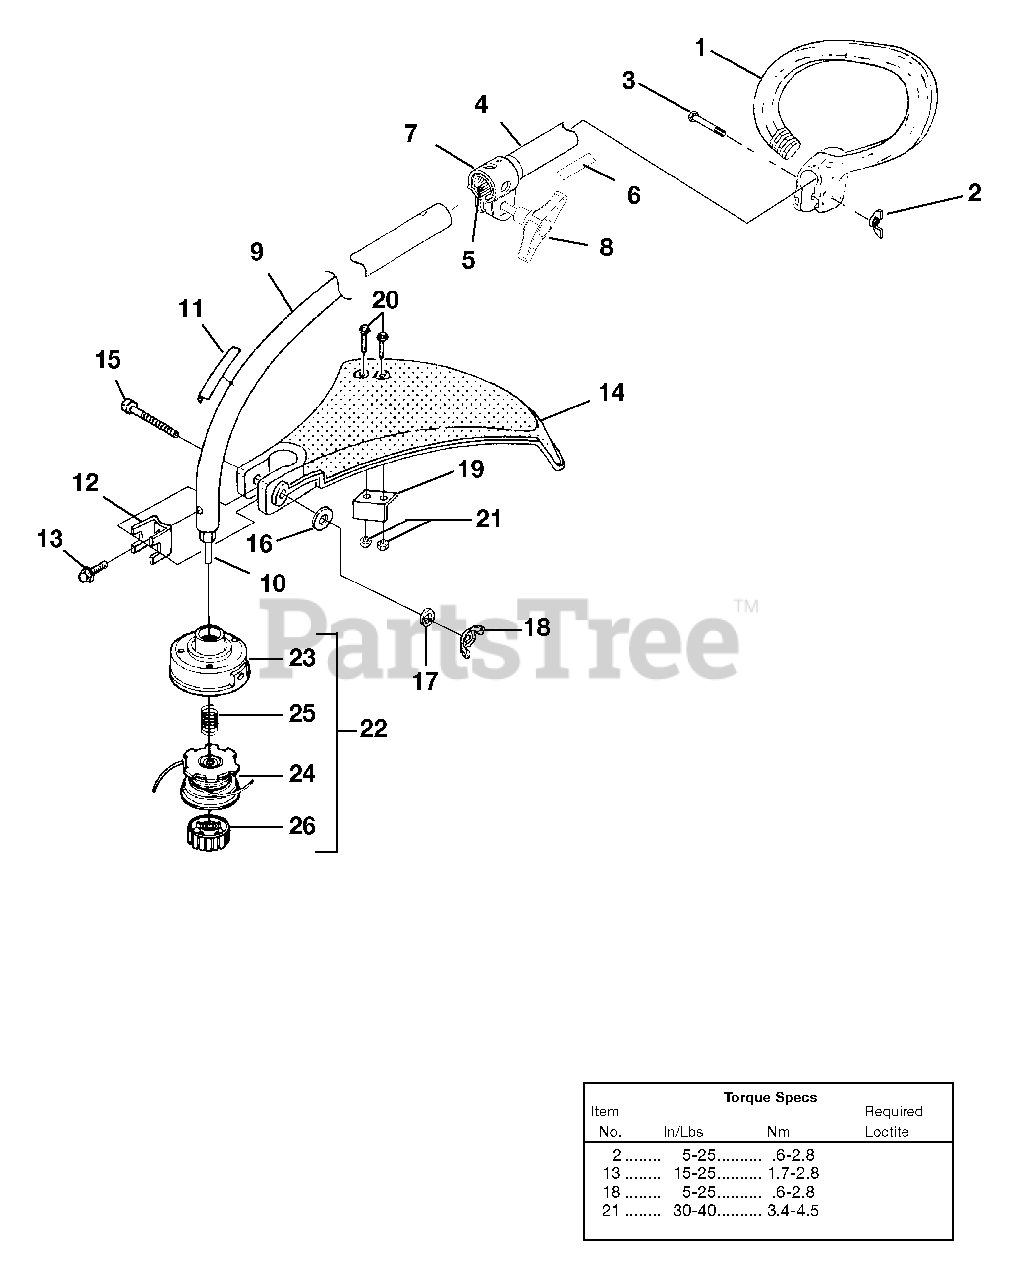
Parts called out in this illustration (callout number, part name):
1	HANDLE-Anti-Vibe
2	NUT-Wing, Washer Faced (1/4-20)
3	SCREW-Cap Hex Hd. (1/4-20 x 2")
4	DRIVESHAFT ASSY. (Upper)
5	FLEXSHAFT w/Collar & Liner
6	DECAL-Warning
7	COUPLER ASSEMBLY
9	DRIVESHAFT HOUSING (Lower)
10	SHAFT-Flex
11	DECAL-Warning
12	CLAMP
13	SCREW-Sems Hex (10-24 X 3/8")
14	DEFLECTOR & BLADE KIT (55 Deg.)
15	SCREW-Cap Hex Hd. (1/4-20 X 2")
16	WASHER-Flat (1/4")
17	WASHER-Lock (1/4")
18	NUT-Wing, Washer Faced (1/4-20)
19	BLADE-Cut-Off
20	SCREW-Mech. Hex Hd. (10-24 X 7/8")
21	NUT-Hex (10-24)
22	STRINGHEAD-Complete (.080")
23	HOUSING & EYELET (Dual Line)
24	SPOOL & STRING (.080")
25	SPRING-Compression
26	RETAINER-Spool (RH Thread, Black)
